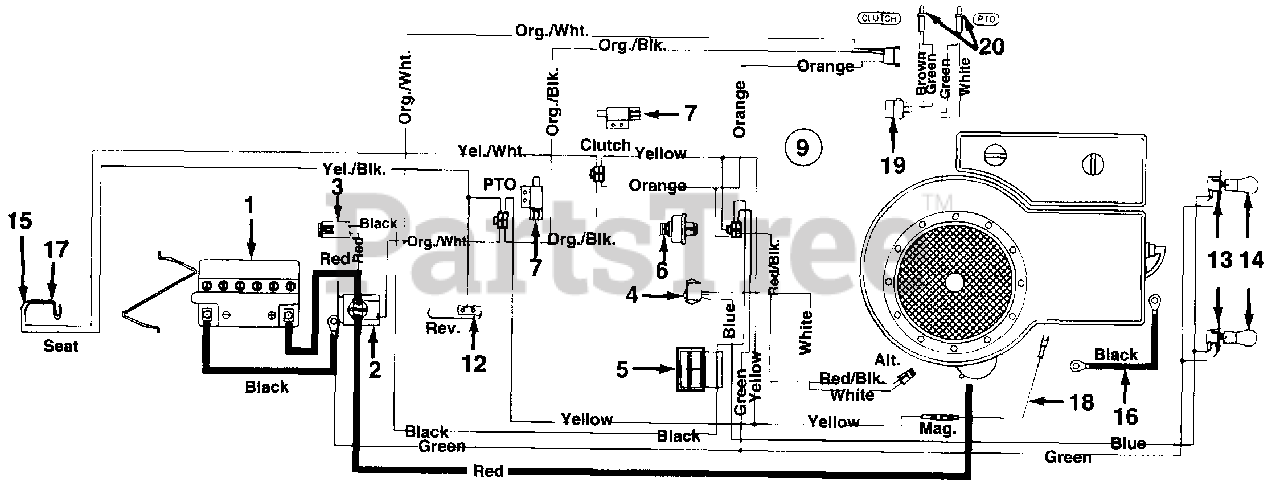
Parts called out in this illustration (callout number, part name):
1	Battery
2	Solenoid
3	Fuse 7.5 Amps
4	Light Switch
5	Ammeter
6	Ignition Switch
7	Safety Switch (Clutch)
9	Wire Harness w/o Ammeter
12	Safety Switch (Reverse)
13	Socket
14	Bulb (Headlight)
15	Safety Switch (Seat)
16	Ground Wire 7.5" Lg.
17	Safety Switch (Seat)
18	Harness Adaptor
19	Monitor Harness
20	Monitor Bulb
